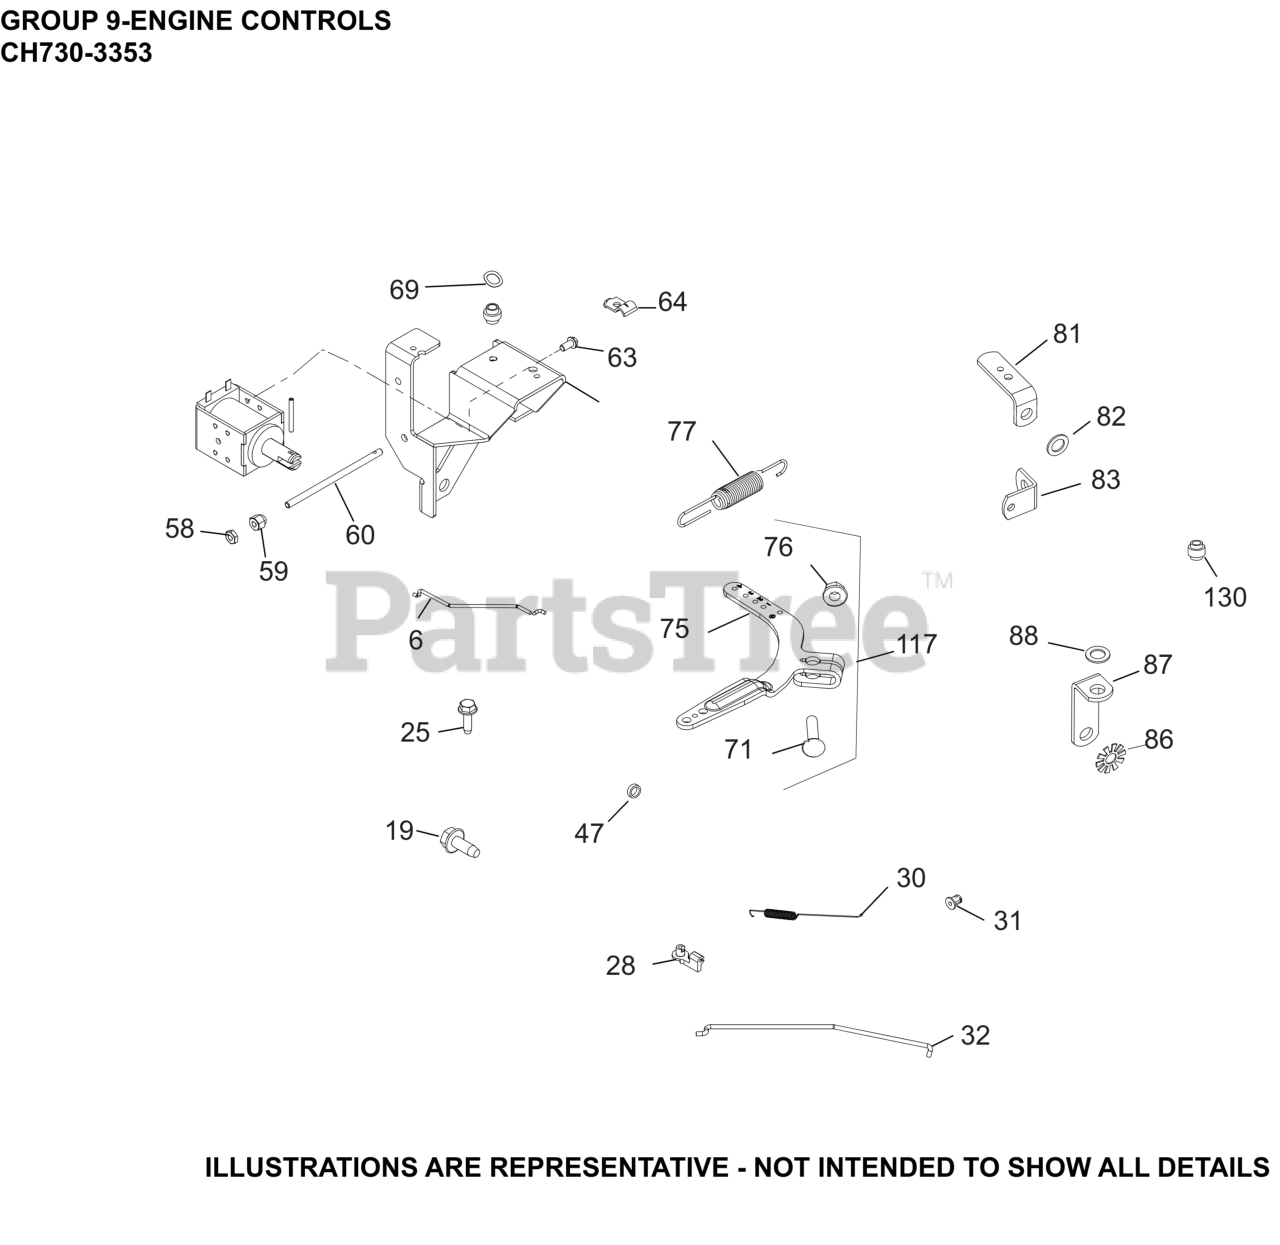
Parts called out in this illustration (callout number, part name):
6	LINKAGE, CHOKE
19	SCREW, THREAD FORMING
25	SCREW, THREAD FORMING
28	BUSHING, THROTTLE LINKAGE
30	SPRING, LINKAGE
31	BUSHING, LINKAGE RETAINING
32	LINKAGE, THROTTLE
58	NUT, MACH SCREW #10-32 GRD 2
59	NUT, ADJUSTING
60	ROD, SPEED CONTROL
63	SCREW,WSH HD TAP #10-24X13/32"
69	WASHER, SPRING 11/32"
71	BOLT, RD HD SQ NECK M6X1.0X25
75	LEVER, GOVERNOR - (#2409069S)
76	NUT, FLG M6X1.0
77	SPRING, GOVERNOR (GREEN)
82	WASHER,INT EXT TOOTH LOCK 1/4"
86	Washer, Int Ext Tooth
87	STRAP, LIFTING
117	LEVER, GOVERNOR ASSEMBLY
NI	LEVER, THROTTLE & CHOKE CONTROL
